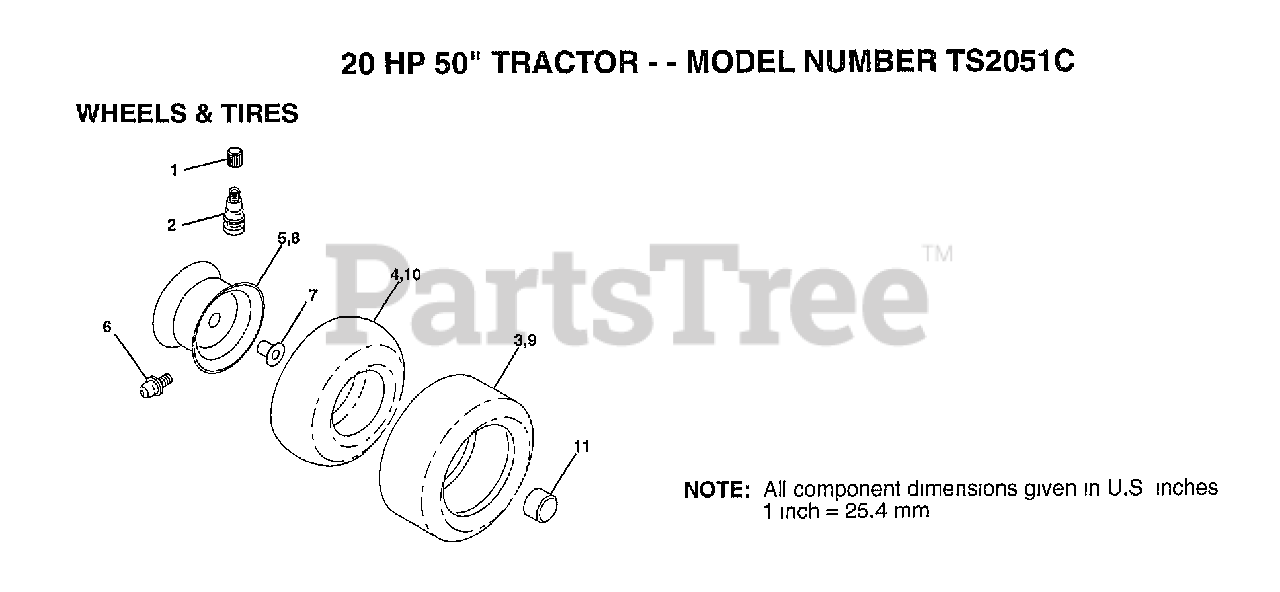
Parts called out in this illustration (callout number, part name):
1	VALVE CAP
2	VALVE STEM LT
4	TUBE.16X6.5/7.5-8
5	RIM.FRONT.
6	ZERK FITTING M
7	"FLANGE, BEARING"
8	"WHEEL,REAR"
10	TUBE.23X8/10-12
11	HUB CAP
12	FITTING LT
